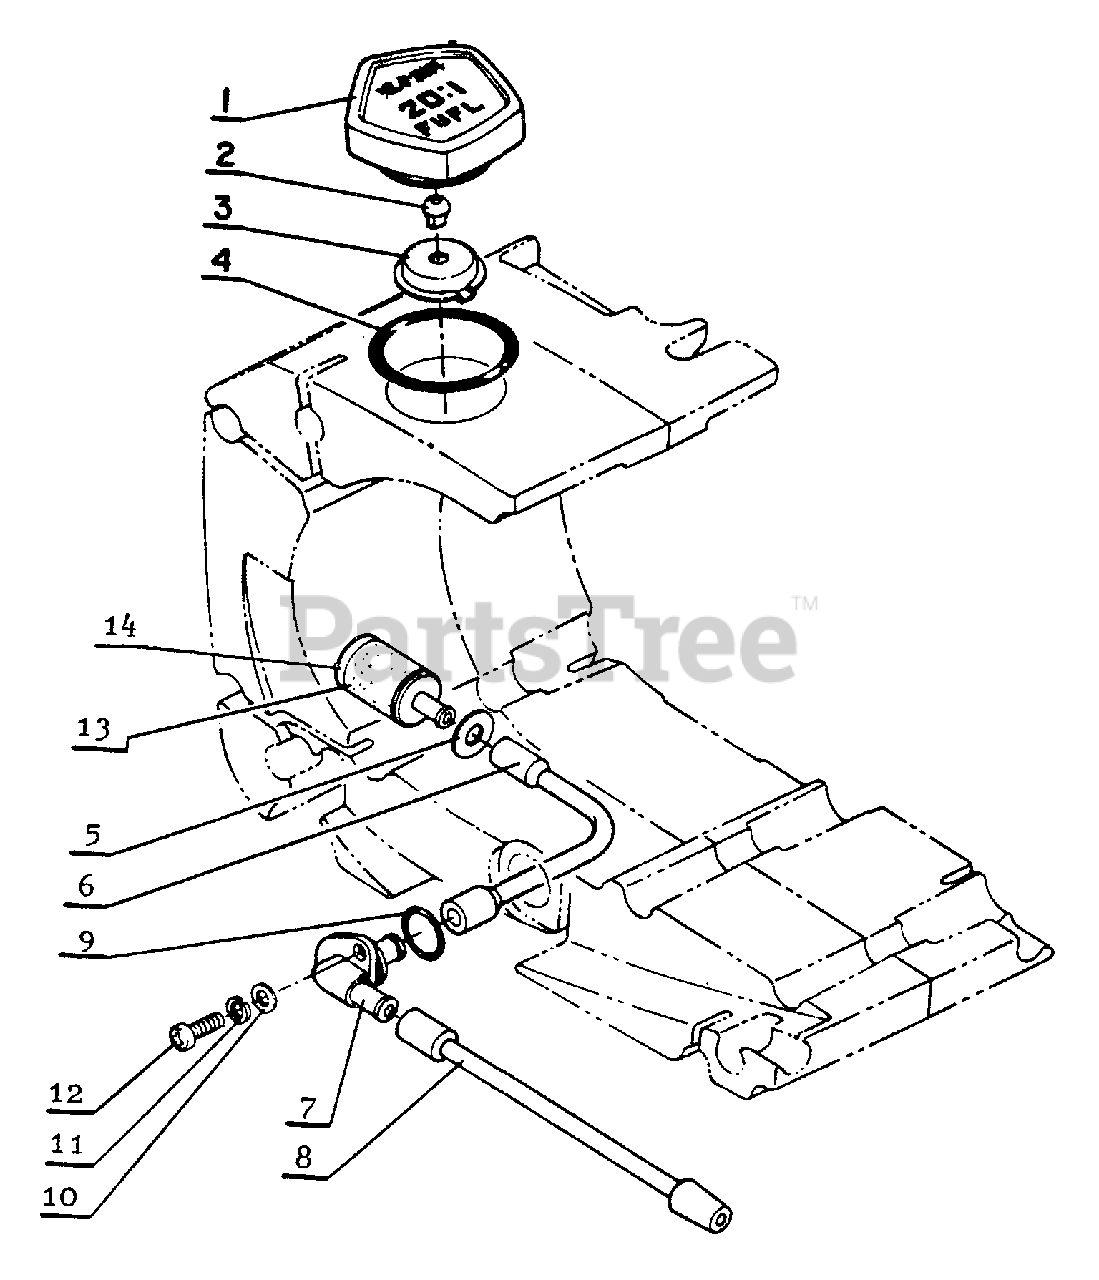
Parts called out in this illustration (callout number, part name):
1	CAP ASSY
3	HOLDER, VENT
4	O-RING - 29
5	WASHER - 6
6	PIPE, FUEL - INNER
7	CONNECTOR, PIPE
8	PIPE - FUEL
9	O-RING - 12
10	WASHER - 4
11	LOCKWASHER - 4
12	SCREW - 4X8
13	FILTER, FUEL
14	FILTER, FUEL
